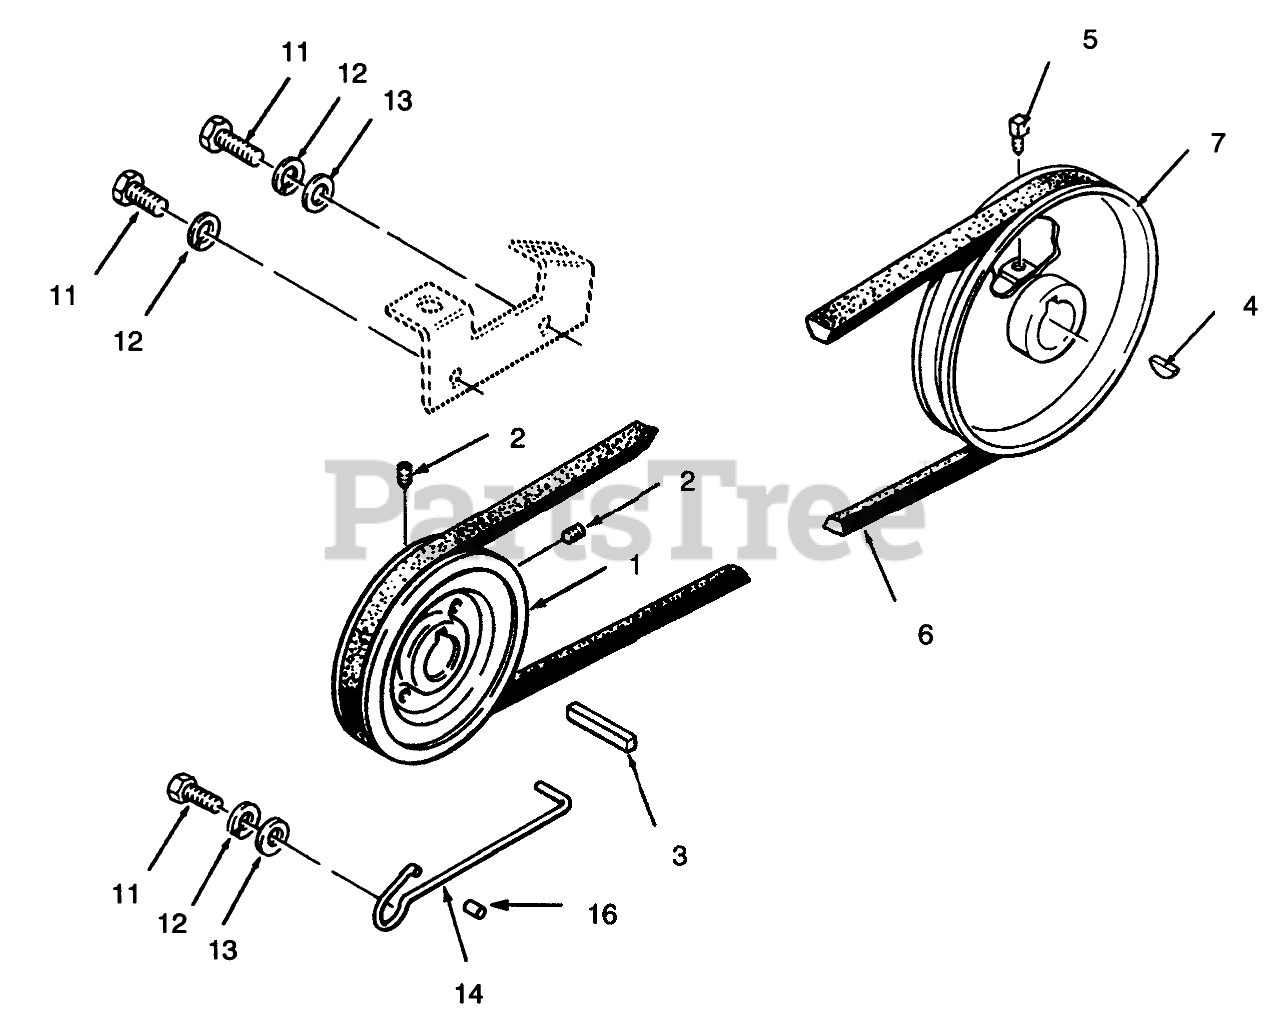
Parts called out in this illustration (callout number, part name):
1	PULLEY
2	SCREW-SET, HSH
4	KEY-HI PRO
5	SCREW-SQH
6	V BELT
7	PULLEY-TRANSMISSION
11	SCREW-HH
12	WASHER-LOCK
13	WASHER-FLAT
14	GUIDE BELT
